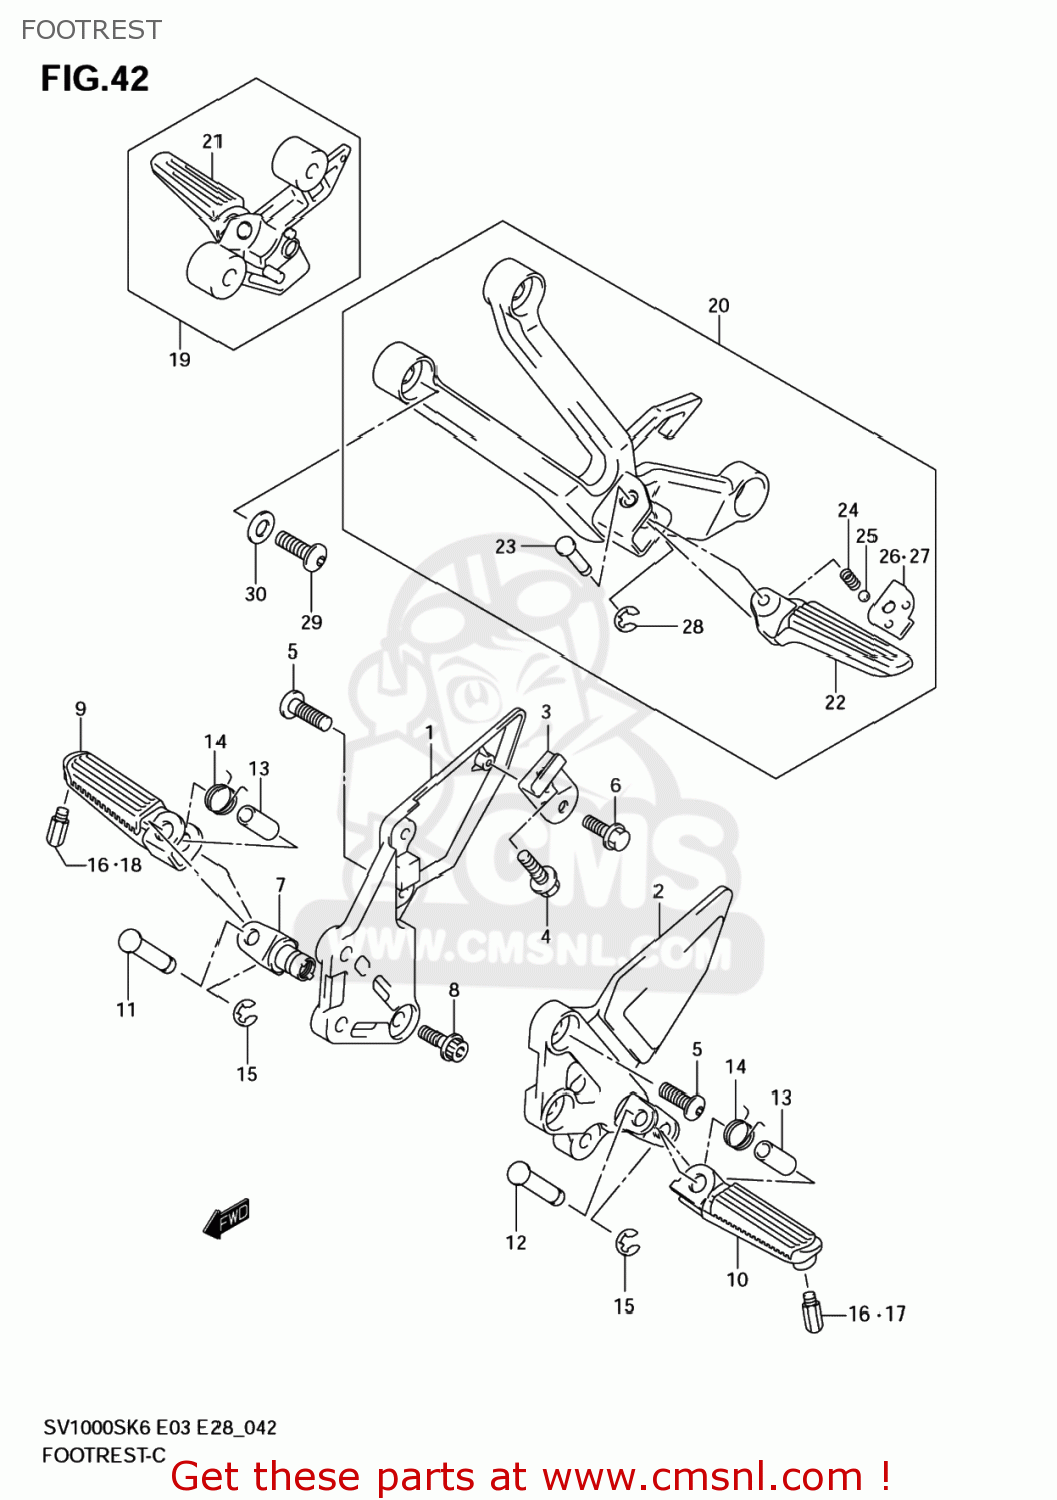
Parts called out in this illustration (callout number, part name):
1	BRACKET,FR FOOTREST,R
2	BRACKET,FR FOOTREST,L
3	REINF,FOOTREST BRACKET
4	BOLT
5	BOLT(8X20)
6	BOLT
7	HOLDER,FOOTREST,R
8	BOLT(10X28)
9	BAR,FR FOOTREST,R
10	BAR,FR FOOTREST,L
11	PIN
12	PIN
13	SPACER(8.1X12X22)
14	SPRING
15	E RING
16	BOLT,BANK SENSOR
17	BOLT,BANK SENSOR
18	BOLT,BANK SENSOR
19	FOOTREST ASSY,PILLION,R
20	FOOTREST ASSY,PILLION,L
21	BAR,PILLION FOOTREST,R
22	BAR,PILLION FOOTREST,L
23	PIN
24	SPRING
25	BALL
26	PLATE,PILLION FOOT,R
27	PLATE,PILLION FOOT,L
28	E RING
29	BOLT(8X23)
30	WASHER
